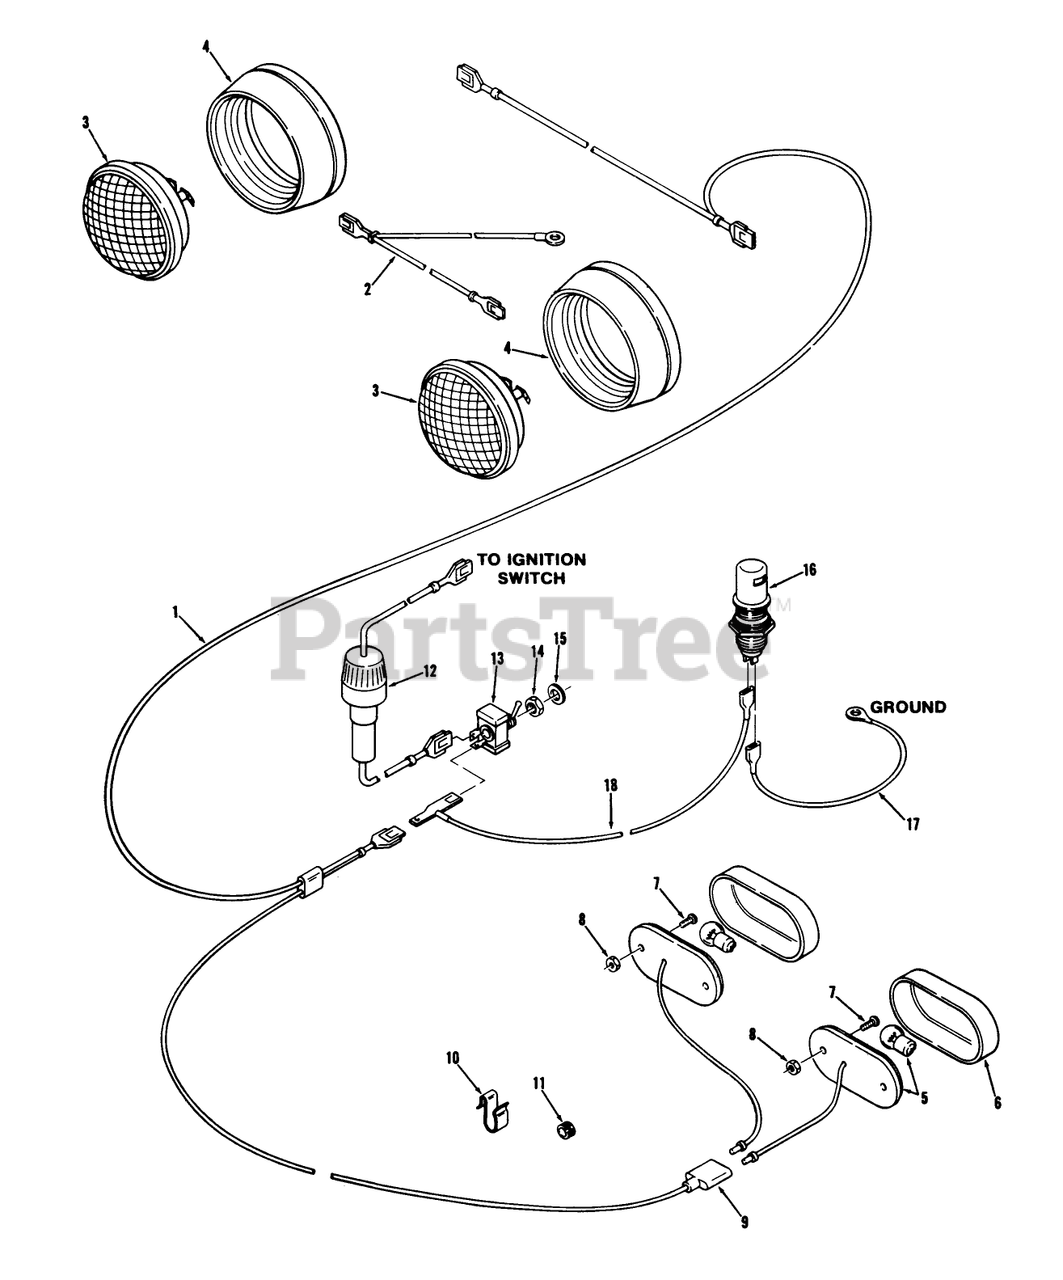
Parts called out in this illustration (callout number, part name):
3	HEADLAMP
8	HEX NUT 10-32 E.S. + + USE 3296-21 + +
13	SWITCH-LIGHTS
15	NUT-HEX
